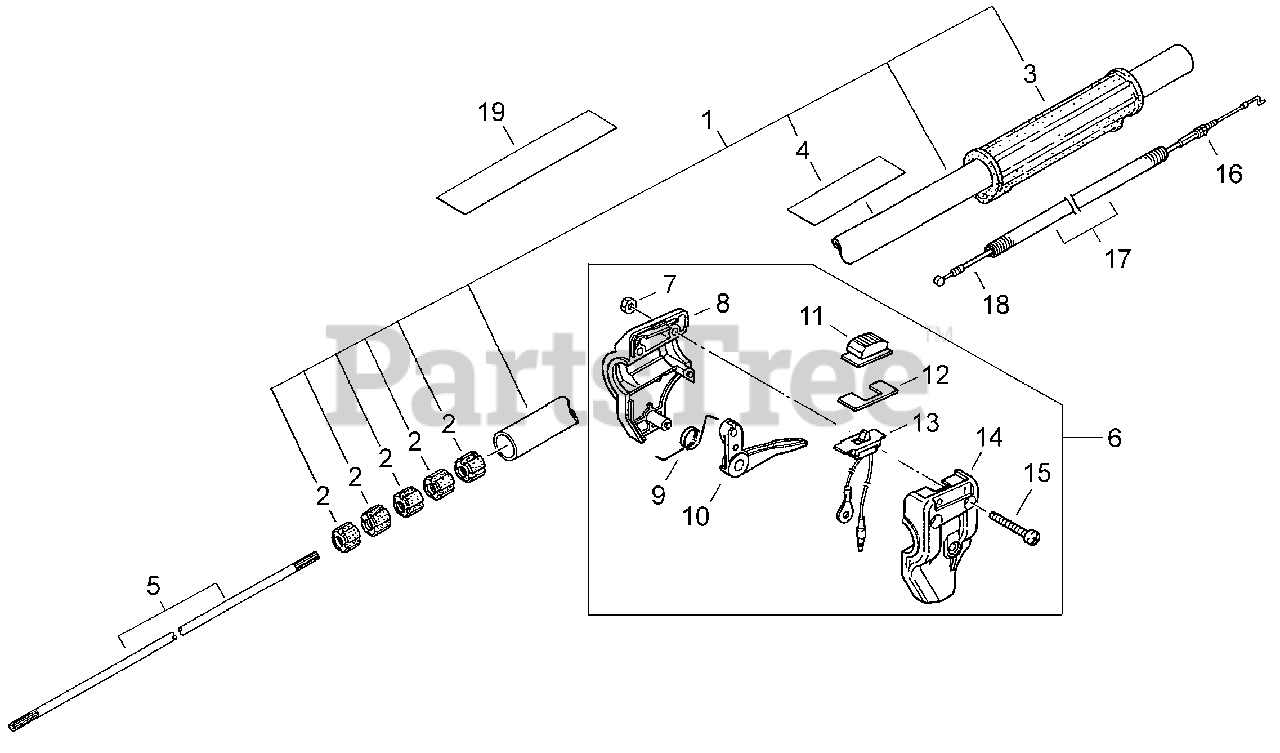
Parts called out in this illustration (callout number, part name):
2	BUSHING
3	GRIP
4	LABEL - CAUTION
5	PIPE, MAIN
6	THROTTLE ASSY
7	NUT - 5
8	BRACKET - RIGHT
9	SPRING, TRIGGER
9-1	MAIN PIPE ASSY
10	TRIGGER, THROTTLE
11	KNOB
12	PLATE, SWITCH
13	SWITCH, IGNITION
14	BRACKET - LEFT
15	SCREW - 5X30
16	NUT - 6
17	FLEXIBLE TUBE
18	CABLE, THROTTLE
19	LABEL - SHINDAIWA
